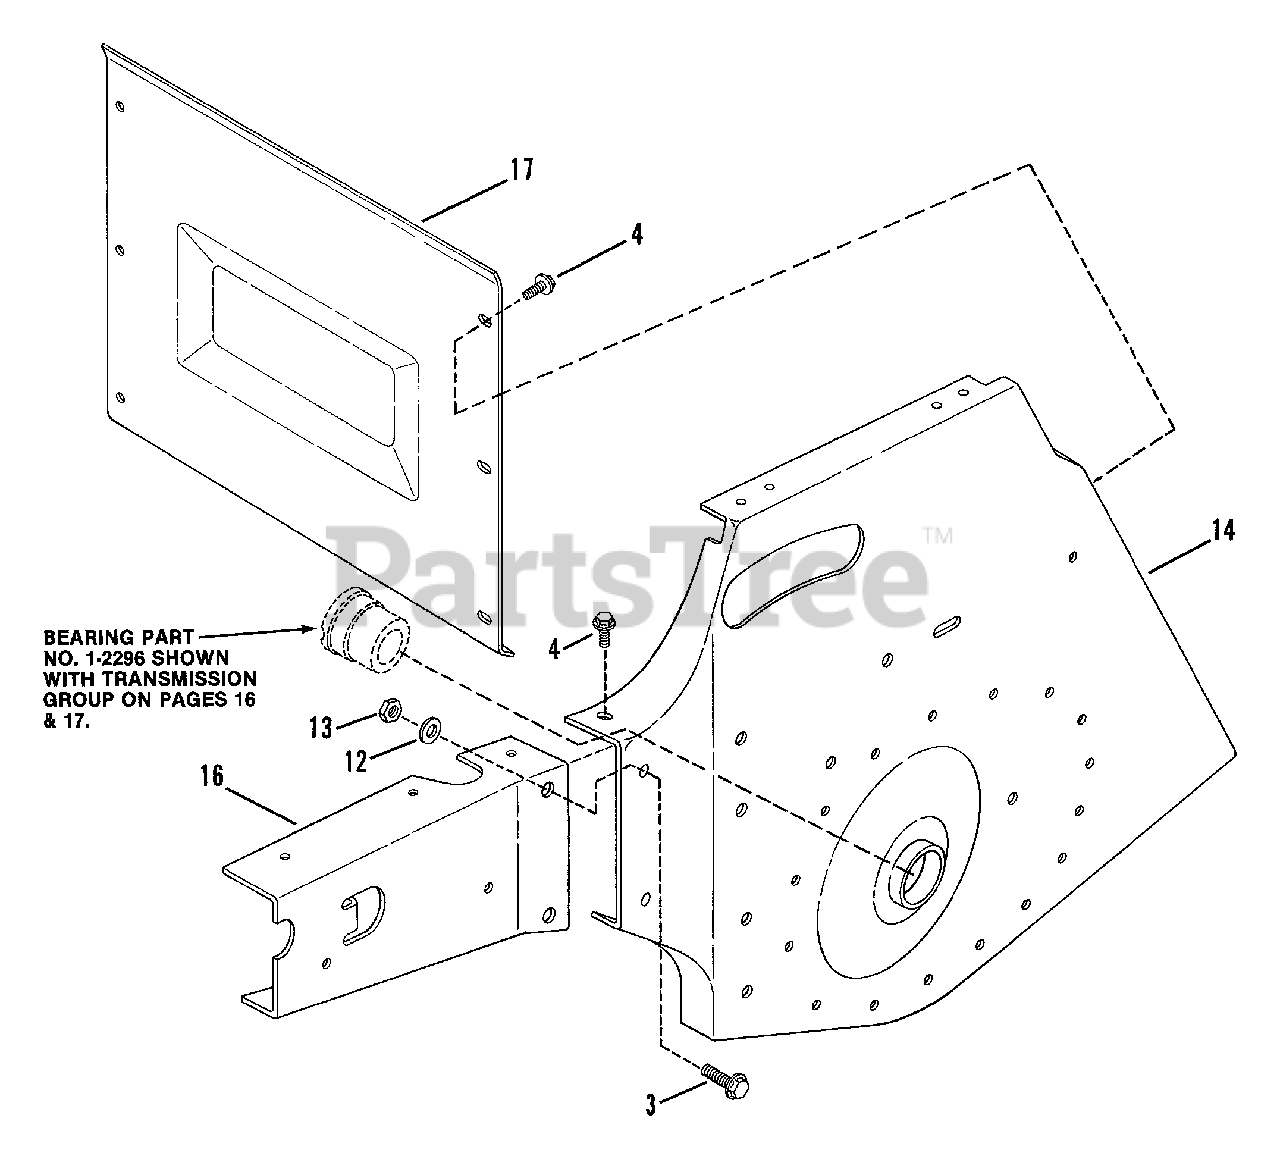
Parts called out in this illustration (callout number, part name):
3	BOLT, 3/8-16x1" Hex Flange Lock
4	SCREW, 5/16-18x5/8" Self-Tapping
12	WASHER, 3/8 SAE
13	NUT, 3/8-16 Center Lock
14	TRANSMISSION SUPPORT, L.H.
16	EXTENSION, Transmission Support, L.H.
17	COVER, Rear
